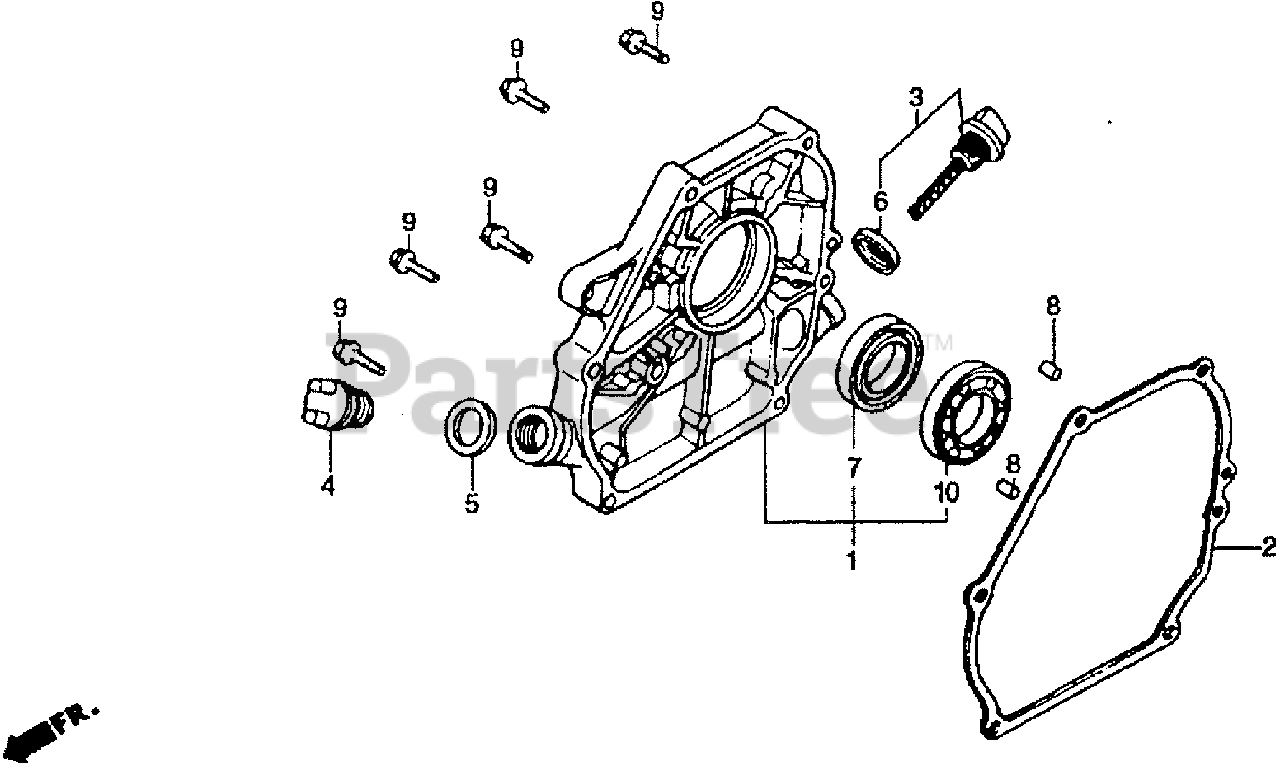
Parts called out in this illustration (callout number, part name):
1	COVER ASSY., CRANKCASE
2	GASKET, CASE COVER (NON-ASBESTOS)
3	CAP ASSY., OIL FILLER
4	CAP, OIL FILLER
5	GASKET, OIL FILLER CAP
6	GASKET, OIL FILLER CAP
7	OIL SEAL (25X41X6)
8	PIN A, DOWEL (8X14)
9	BOLT, FLANGE (8X32)
10	BEARING, RADIAL BALL (6205)
